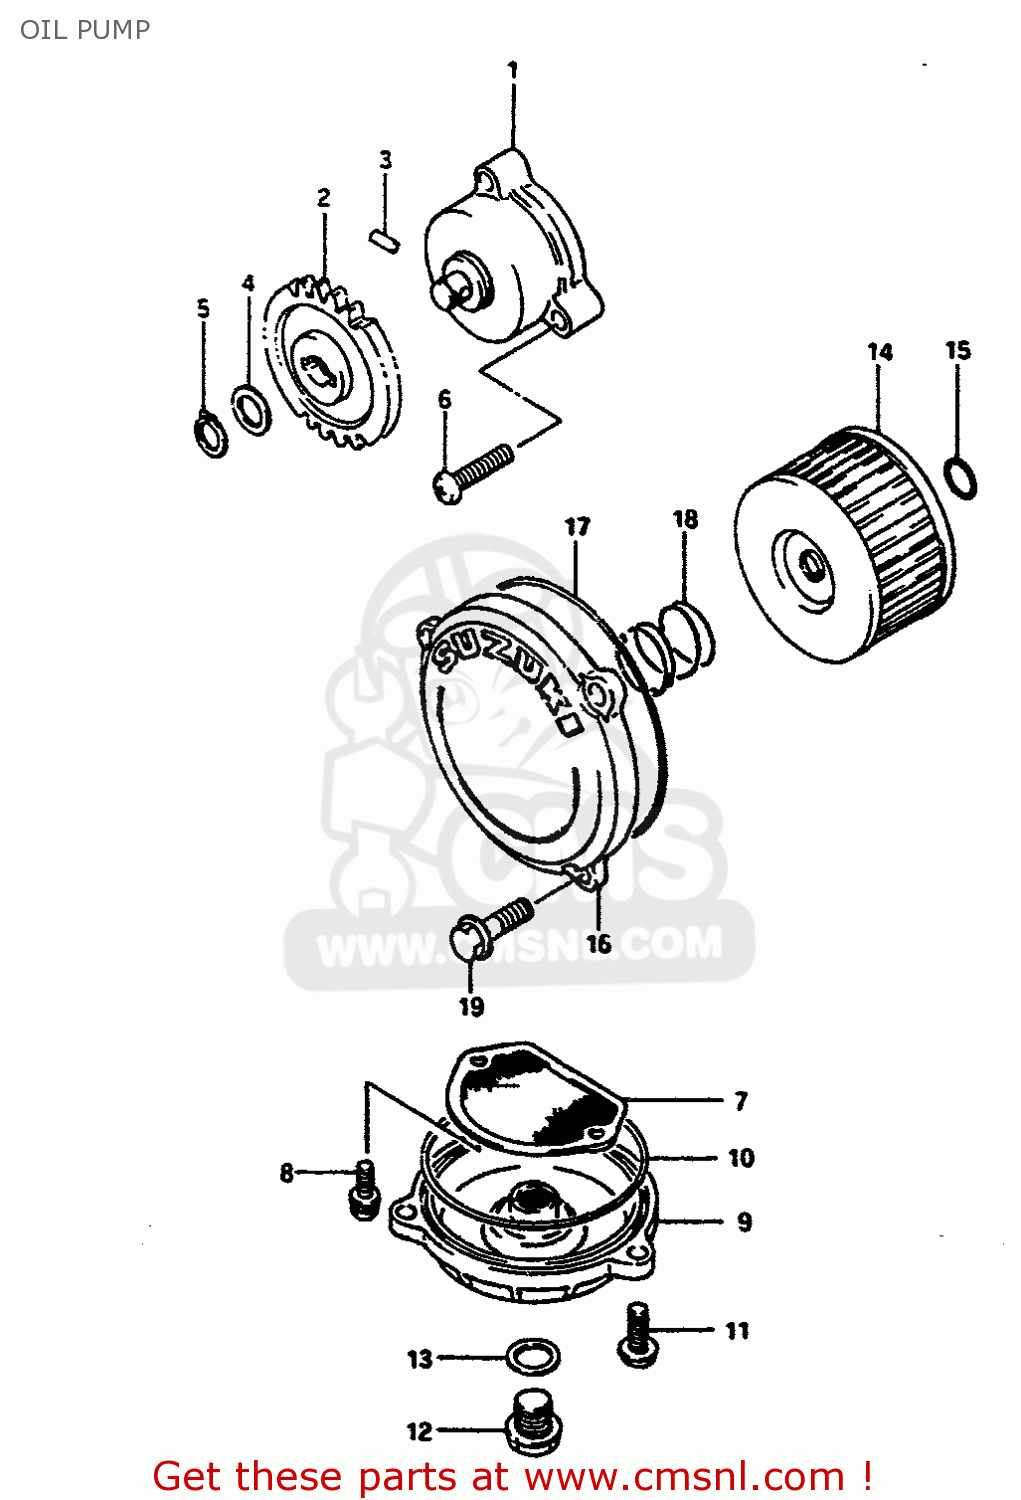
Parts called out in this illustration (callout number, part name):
1	PUMP ASSY,ENGINE OIL
2	GEAR,OIL PUMP DRIVEN
3	PIN(4X15.8)
4	SHIM
5	CIRCLIP,10MM
6	SCREW
7	STRAINER,ENGINE OIL
8	SCREW
9	CAP,OIL STRAINER
10	O RING(D:2.4,ID:85)
11	BOLT 6X20
12	PLUG
13	GASKET(14X19.2X2) (NAS)
14	FILTER,ENGINE OIL
15	O RING(D:2.4,ID:15.8)
16	CAP,OIL FILTER
17	O RING(D:2.4,ID:73)
18	SPRING
19	BOLT
